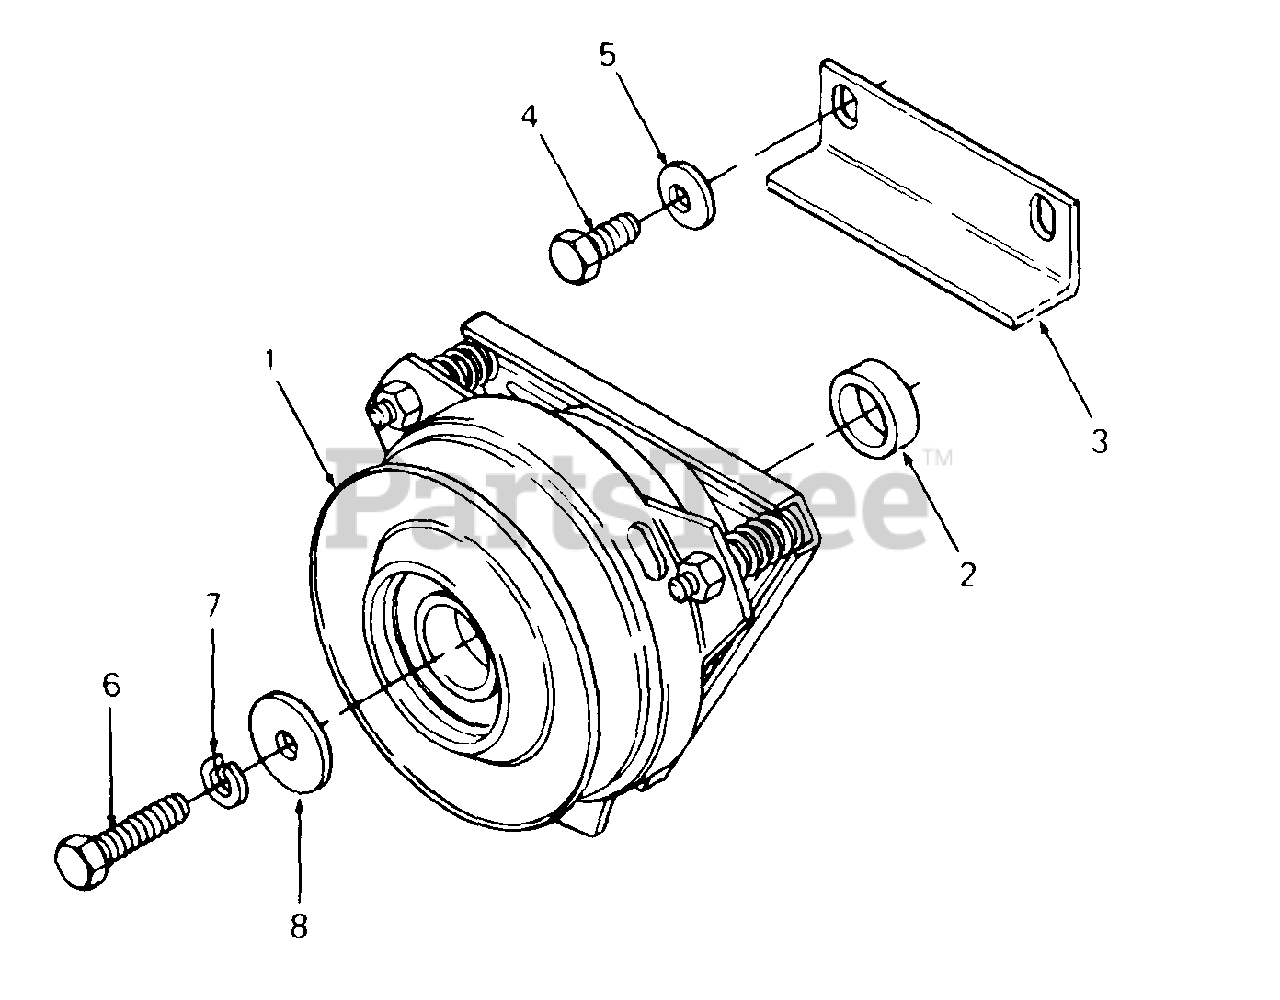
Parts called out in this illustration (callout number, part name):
1	Clutch, PTO
2	Spacer
5	Washer, Bell, .45 X 1.0 X .062 Thk
6	Screw, Hex Cap, 3/8-24 X 2.00 Lg GR5
7	Washer, Lock, 3/8
8	Washer, Flat, .445 X 1.5 X .172 Thk
